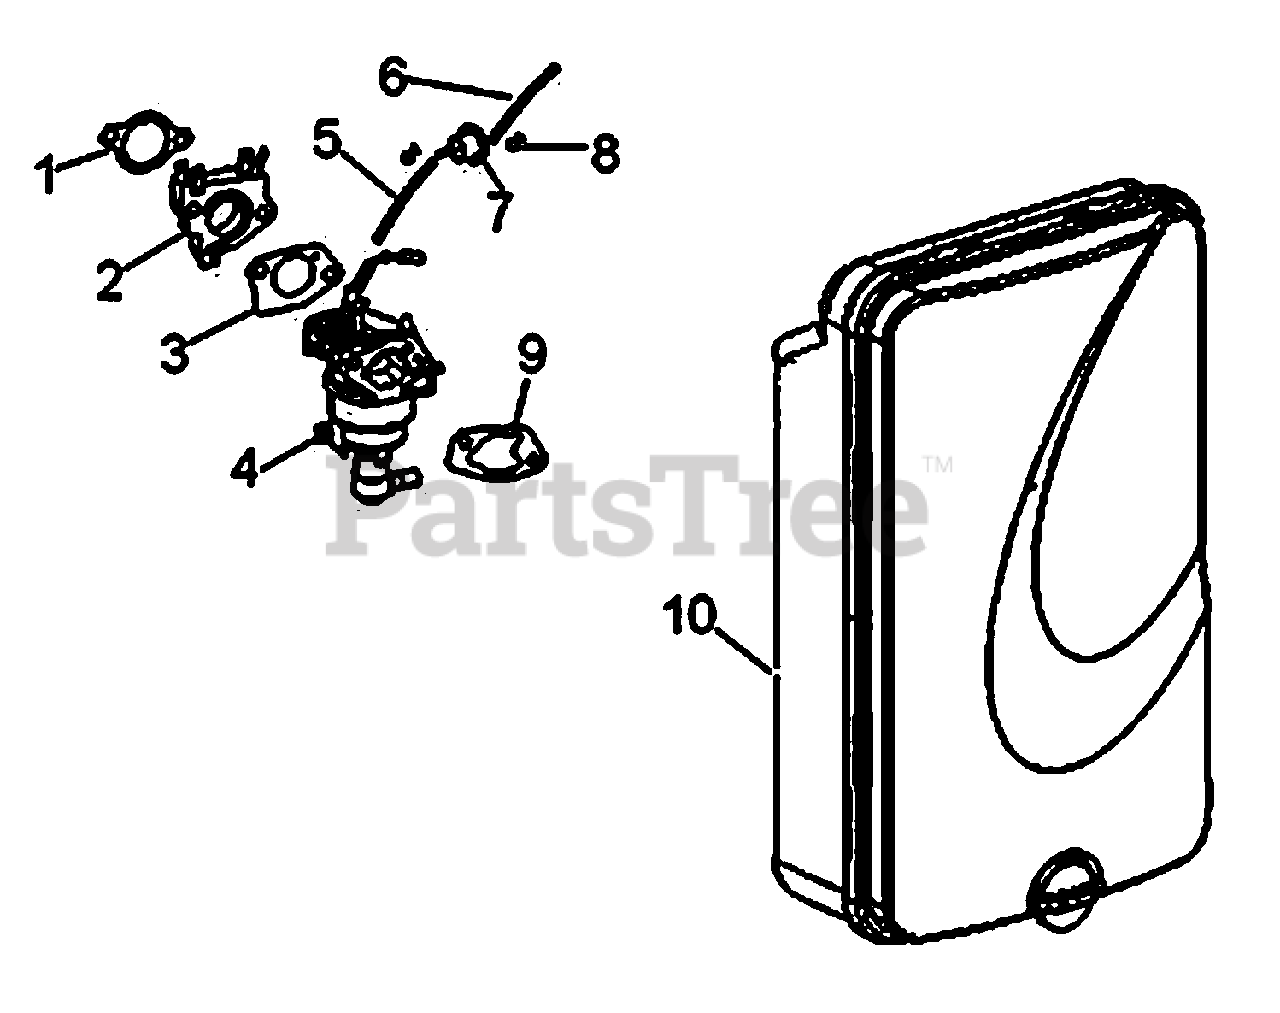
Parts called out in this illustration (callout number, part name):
1	GASKET, CARBURETOR
2	SPACER, CARBURETOR
3	GASKET, CARBURETOR
4	CARBURETOR ASSY.
5	TUBE, FUEL
6	TUBE, FUEL
9	GASKET, CARBURETOR
10	AIR CLEANER
